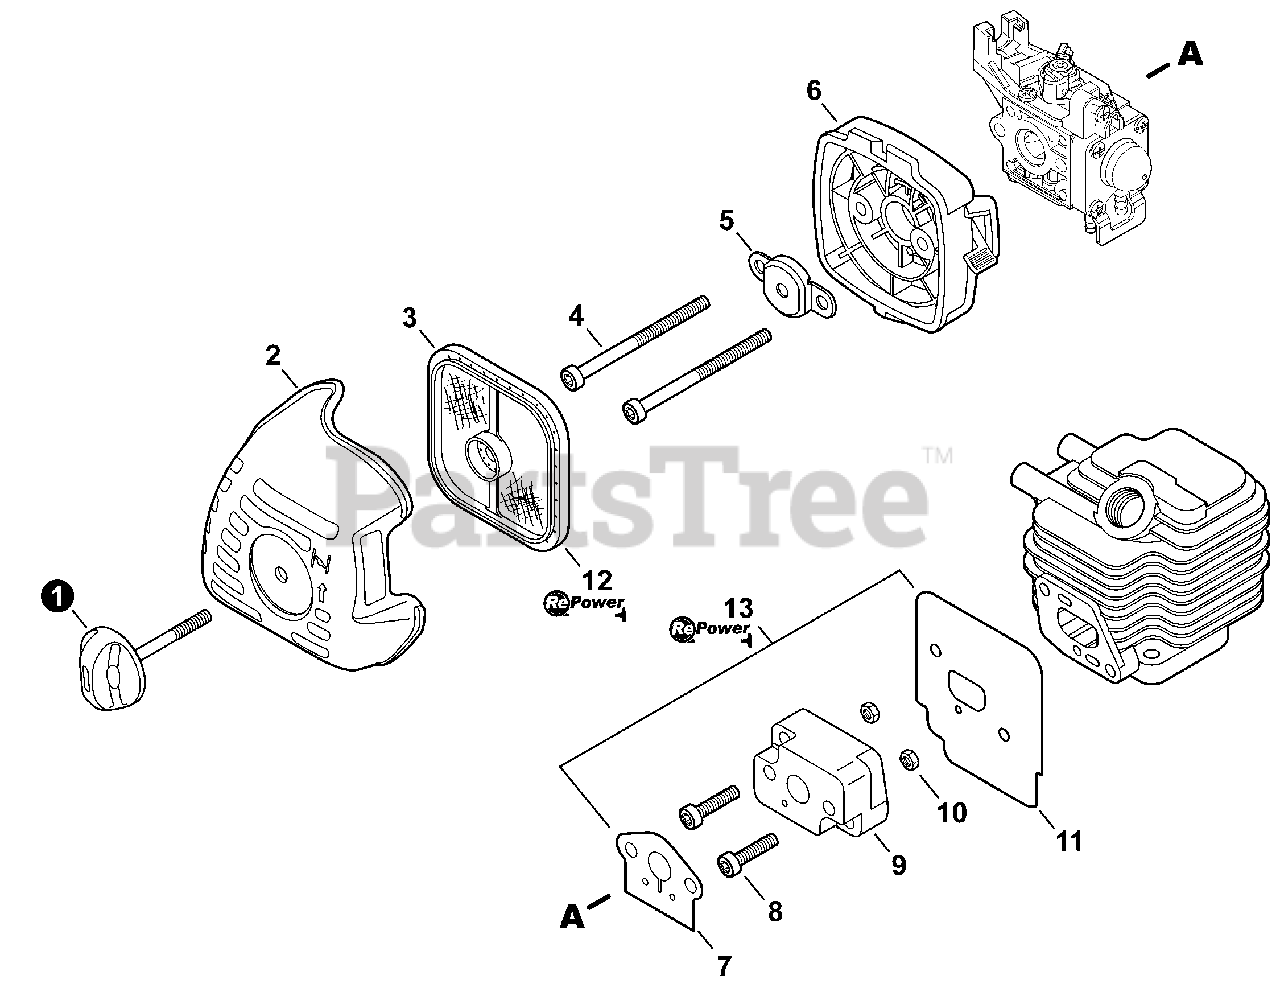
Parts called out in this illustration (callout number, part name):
1	THUMBSCREW
2	COVER, AIR FILTER
3	FILTER, AIR - DOUBLE LAYER
4	BOLT, TORX 5x65
5	PLATE, PREVENT
6	CASE ASSY, AIR FILTER
7	GASKET, INTAKE
8	BOLT, TORX 5x20
9	INSULATOR, INTAKE
11	HEAT SHIELD, INTAKE
12	TUNE-UP KIT - REPOWER
13	GASKET KIT: ENGINE, INTAKE, EXHAUST
